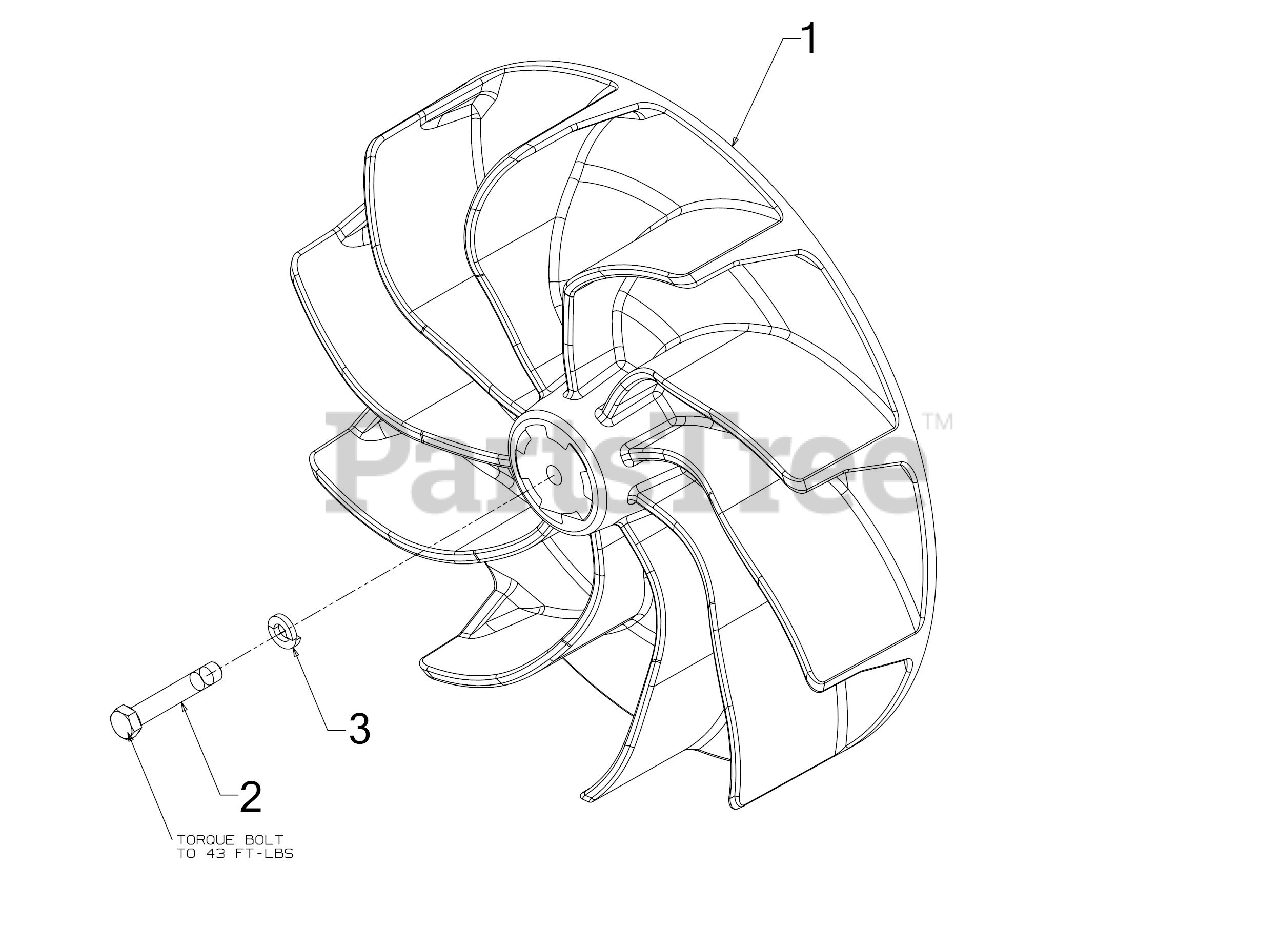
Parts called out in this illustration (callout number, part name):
1	BLOWER IMPELLER ASSEMBLY
2	SCREW 3/8-24X2.25 GR8
3	LOCK WASHER 3/8HD
